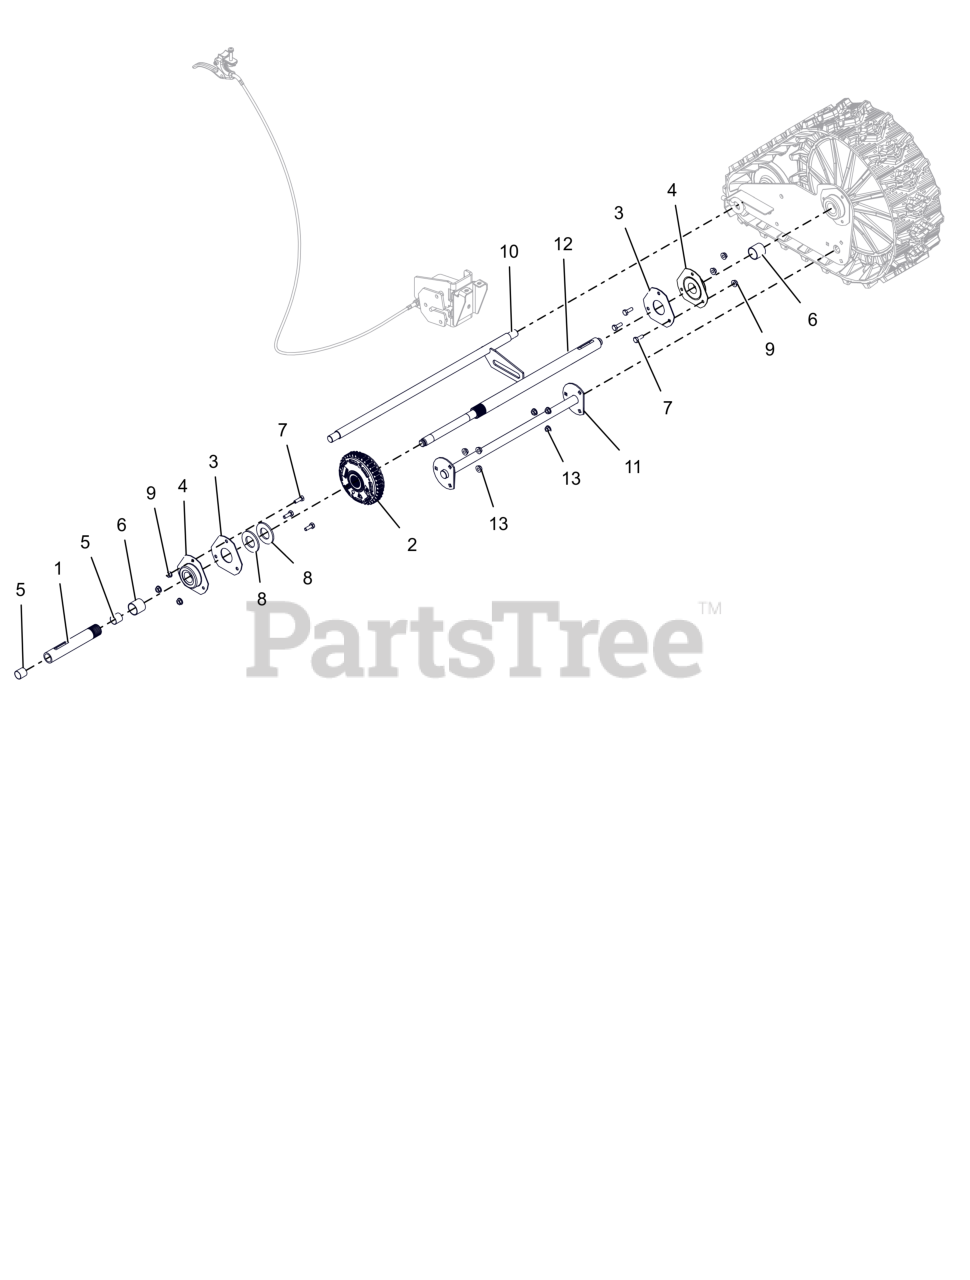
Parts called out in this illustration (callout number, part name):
1	AXLE, SHORT-W/BUSHINGS
2	DIFFERENTIAL, AUTOMATIC
3	PLATE, BEARING SPACER
4	BRG-FLG 1.003/1.000 3 BOLT
5	BSHG-SLV .706X.764X.75 BRZ
6	BSHG-SLV, 1.012X1.125X1.00
7	BLT, HEX .25-20X.75 G5 ZCC
8	WSHR, FLT 1.062X2.000X.134 ZCC
9	NUT-LK-CTR-FLG .25-20 ZC120
10	AXLE, REAR-BWT WLDMT
11	SUPPORT, FRONT-BWT
12	AXLE, LONG-TRACK DIFFERENTIAL
13	NUT-LK-TOP-FLG .250-20 GF ZCC
